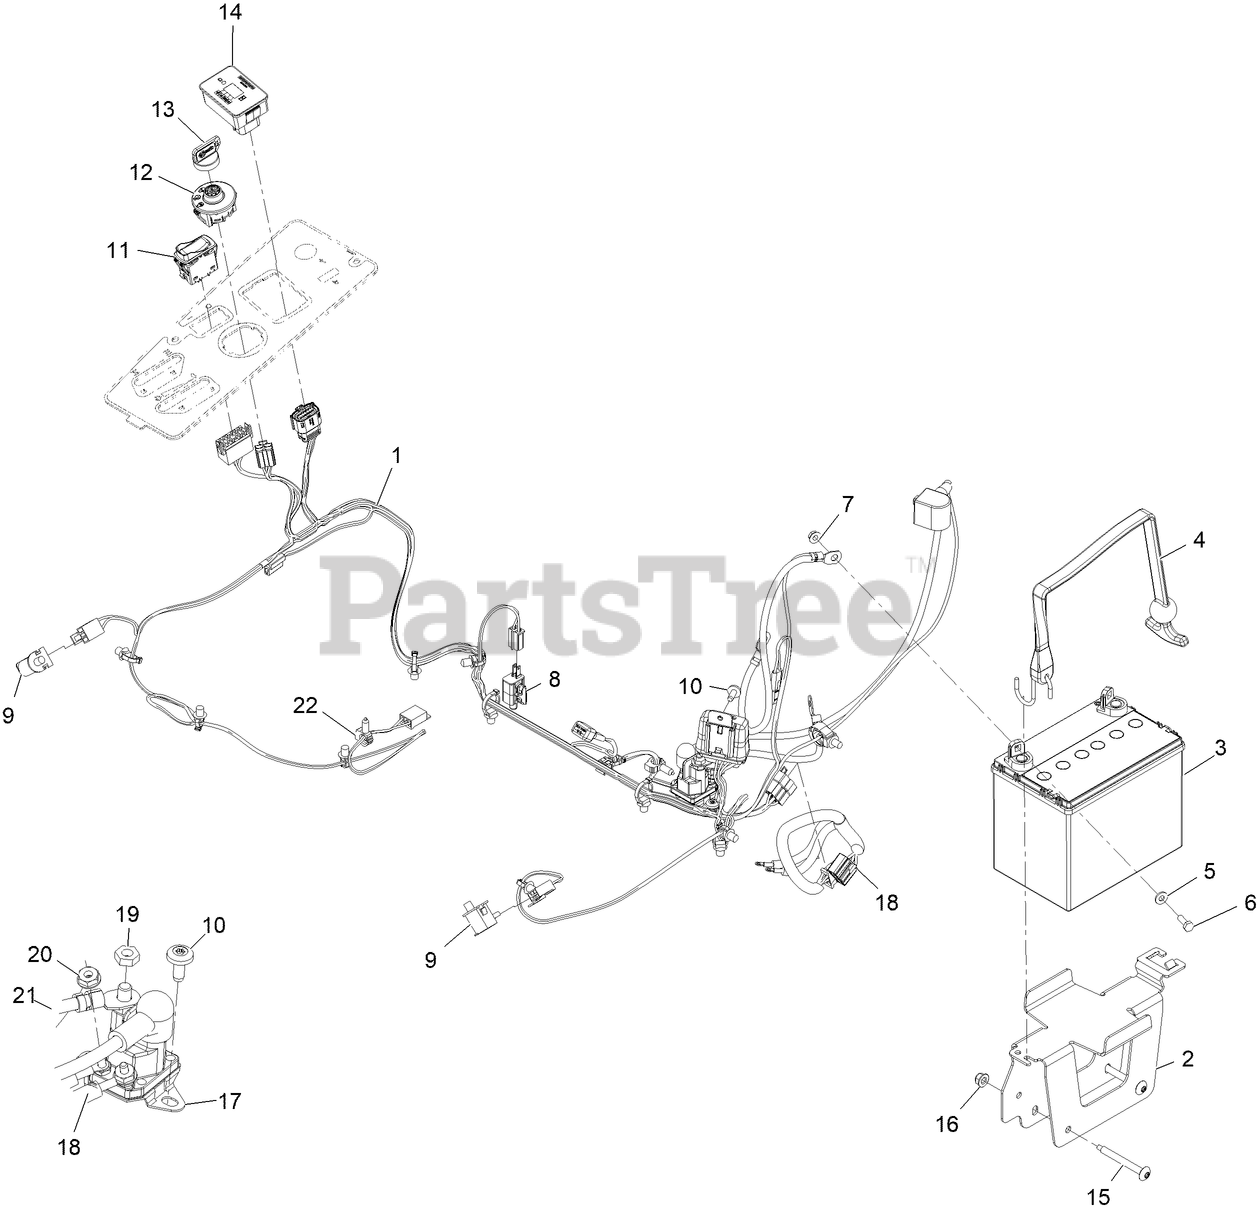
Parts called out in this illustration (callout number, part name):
1	Harness-Main
2	TRAY-BATTERY
3	Battery
4	STRAP, BUNGEE
5	WASHER-FLAT
6	SCREW-HH
9	SWITCH-BAIL
10	SCREW-TORX
11	SWITCH-ROCKER, ON-NONE-ON
12	SWITCH-IGNITION
13	KEYS-IGNITION (SPARE PAIR
13	KEY-IGNITION
14	MODULE ASM
15	SCREW-TORX
16	NUT-HF, NI
17	SOLENOID
18	ADAPTER-HARNESS, WIRE
19	NUT-JAM
20	NUT-KEPS
21	CABLE-BATTERY, POSITIVE
22	CLIP-HARNESS
